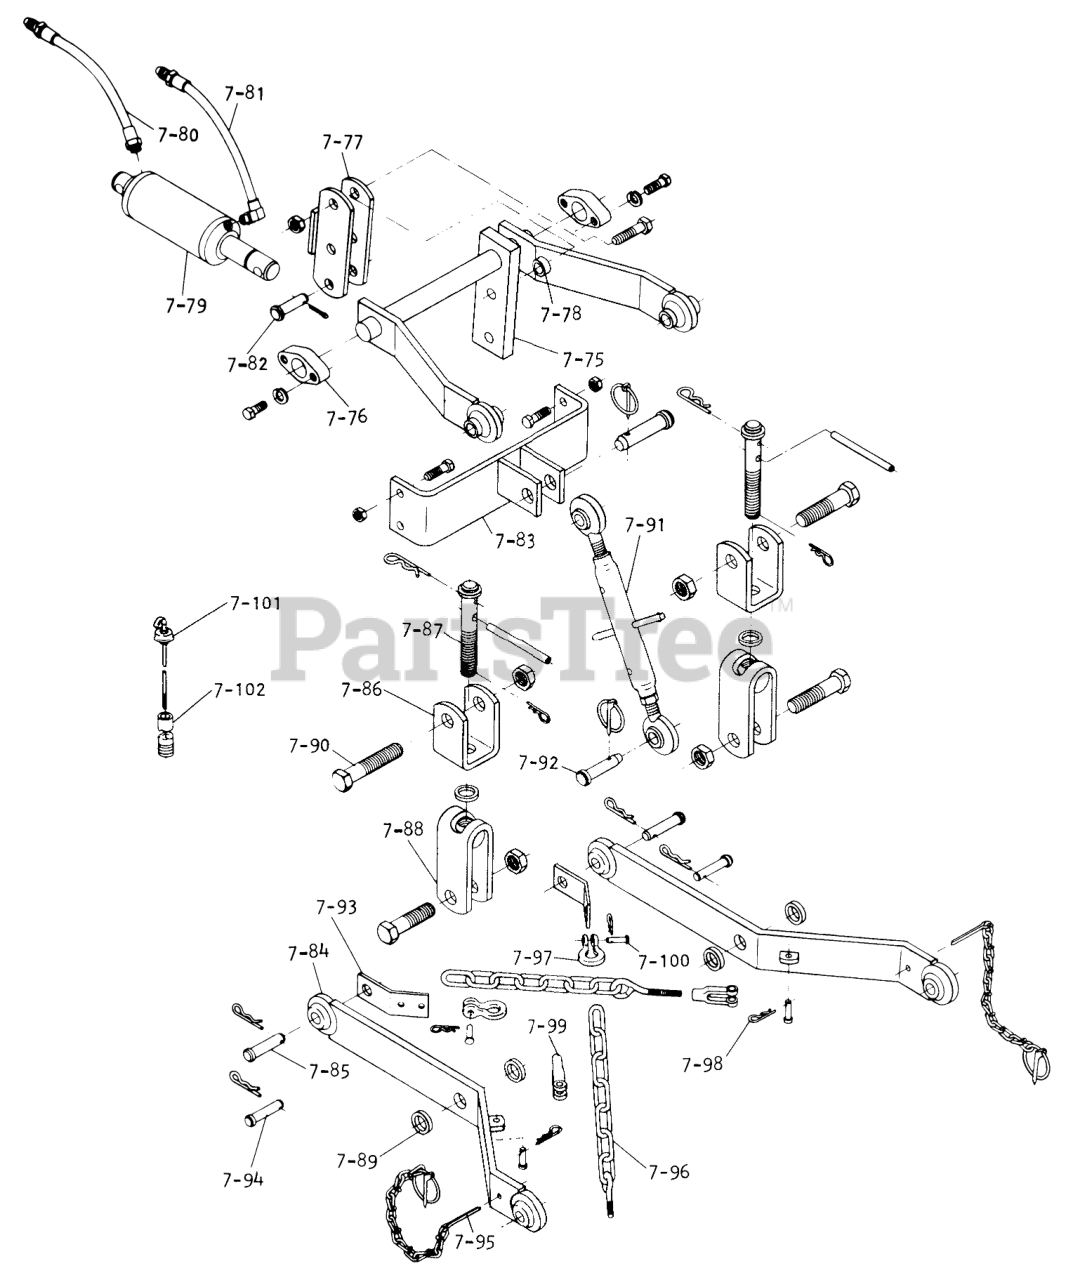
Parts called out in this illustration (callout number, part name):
7-75	Lift Assembly
7-76	BLOCK R
7-77	Pivot Assembly
7-78	SPACER
7-79	Cylinder
7-80	Hose-Hydraulic
7-81	Hose-Hydraulic
7-82	PIN CLEVIS .50 DIA
7-83	Upper Link Assembly
7-84	Lower Hitch Link
7-85	PIN 5/8 DIA LINK ATT
7-86	LIFT BAR
7-87	Adjust Rod Assembly
7-88	Adjuster
7-89	SPACER
7-90	Bolt-Hex 3/4-10 x 3 1/2
7-91	Link-Upper
7-92	PIN HITCH UPPER LINK
7-93	BRKT CHAIN ATTACHING
7-94	PIN CLEVIS .50 DIA
7-95	Klik Pin
7-96	Sway Chain
7-97	Clevis
7-98	Hairpin
7-99	CLEVIS
7-101	Dipstick
7-102	Nipple
